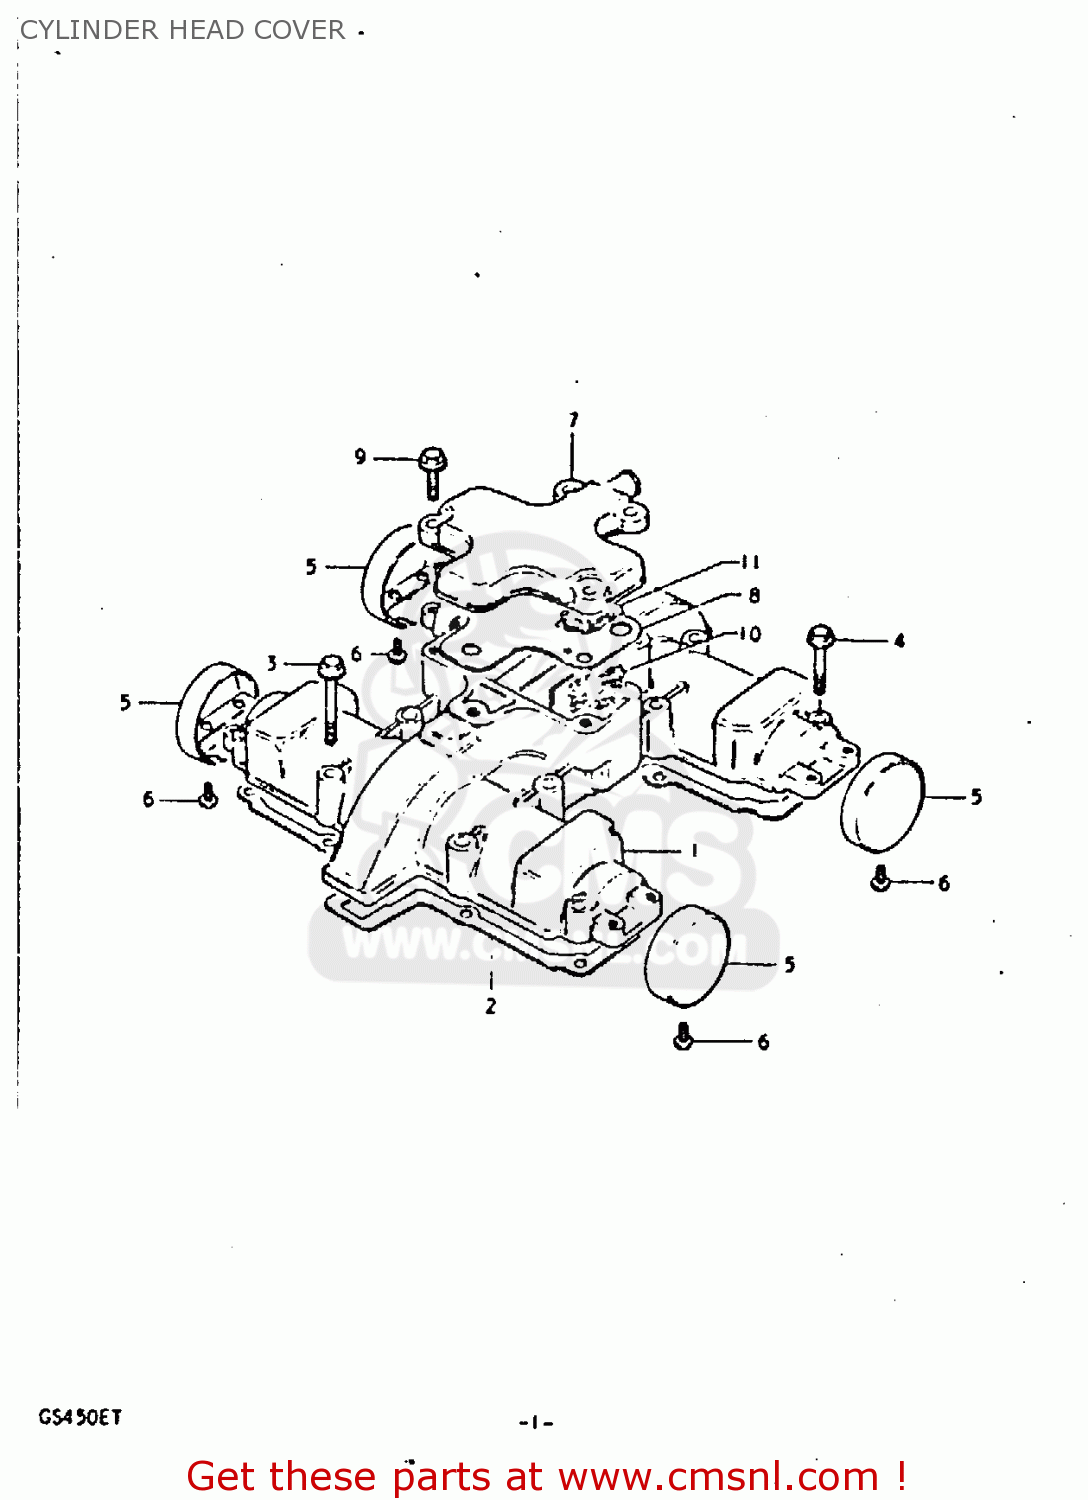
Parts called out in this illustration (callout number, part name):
1	COVER,CYLINDER HEAD
2	GASKET,CYLINDER HEAD COVER (MCA)
3	BOLT
4	BOLT
5	CAP,CYLINDER HEAD COVER
6	SCREW
7	COVER,BREATHER
8	GASKET (MCA)
9	BOLT,REAR
10	COVER,BREATHER
11	SEPARATOR,OIL BREATHER
